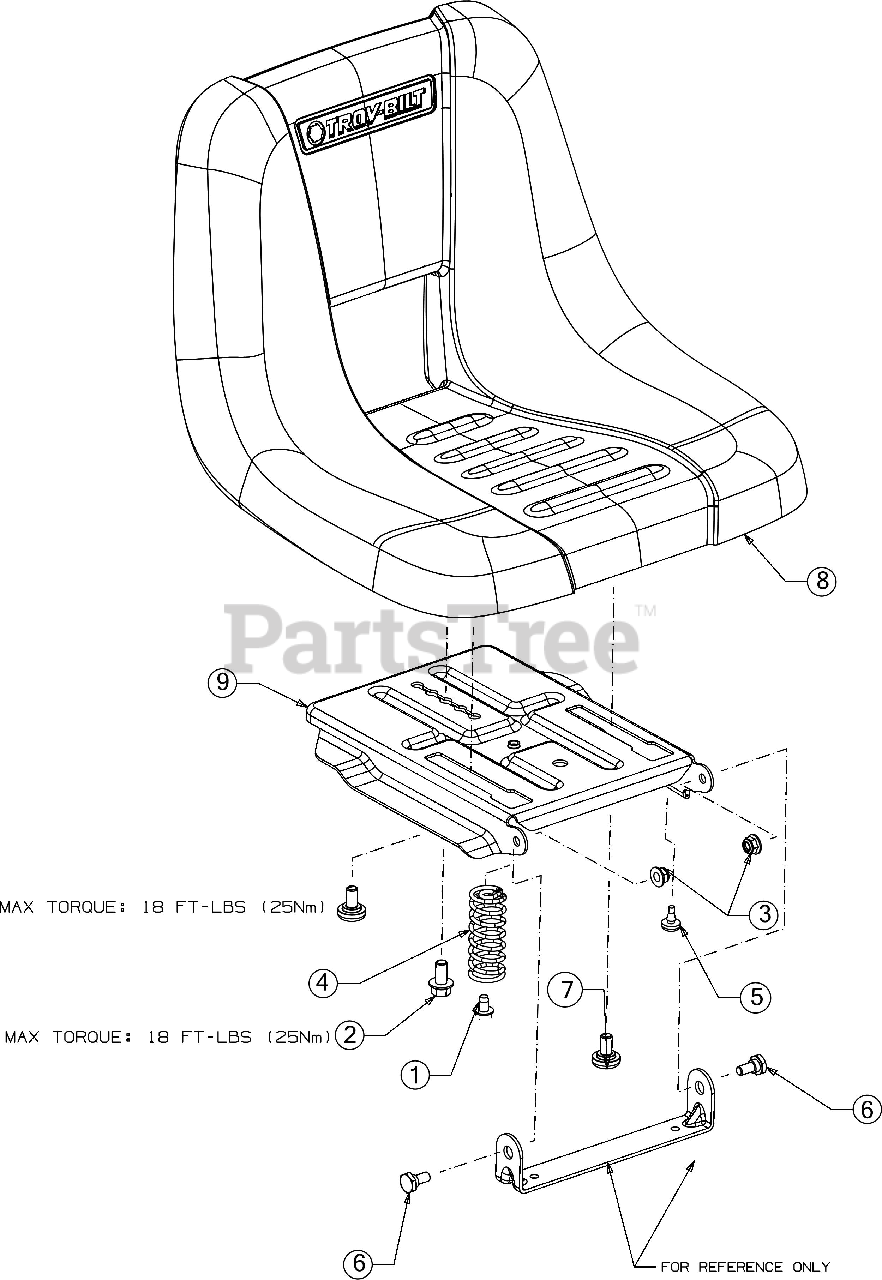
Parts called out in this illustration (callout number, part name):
1	SCREW 5/16-18 x .500
2	SCREW 3/8-16 x .750 GR5
3	FLANGE LOCK NUT 5/16-18
4	SEAT SPRING
5	RUBBER BUMPER
6	SHOULDER SCREW .437
7	SHOULDER SCREW.625 x .110:3/8-16
8	MEDIUM BACK SEAT
9	MANUAL SEAT ADJUSTMENT BRACKET
